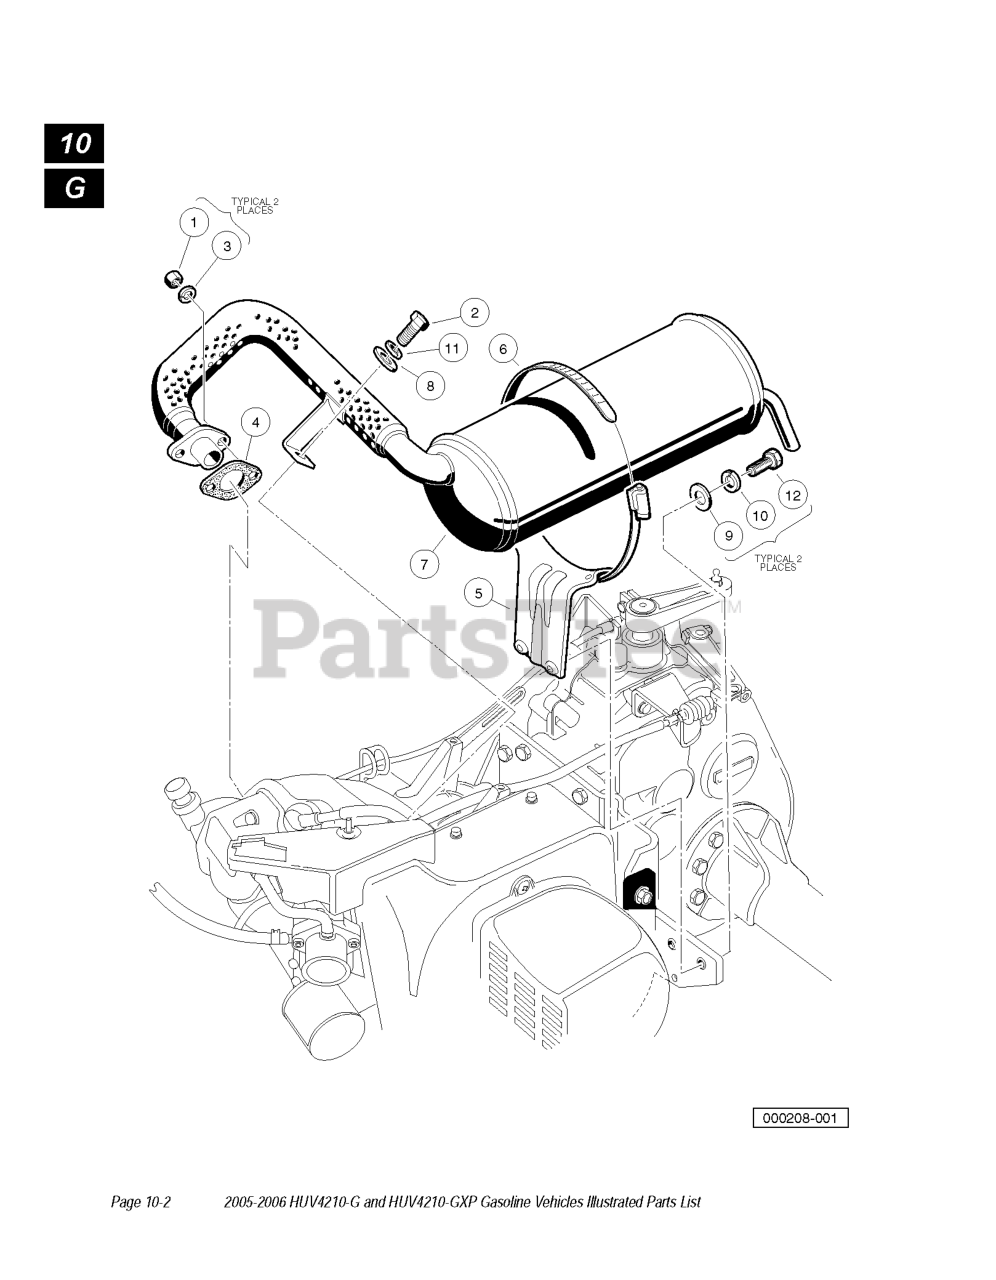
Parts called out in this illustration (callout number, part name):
1	NUT, M8-1.25 HEX
2	SCREW, M8-125 X 22 HEX GR.8.8
4	GASKET, OHV EXHAUST
5	BRACKET, MUFFLER MOUNTING
6	CLAMP, 5" MUFFLER HOSE
7	EXHAUST SYSTEM, FE290
8	WASHER, 5/16 TYPE A FLAT
9	WASHER 1/4 FLAT
10	LOCKWASHER, 1/4 HELICAL SPLIT
11	LOCKWASHER, 5/16 SPLIT
12	SCREW, 1/4-20 X .75 HEX
